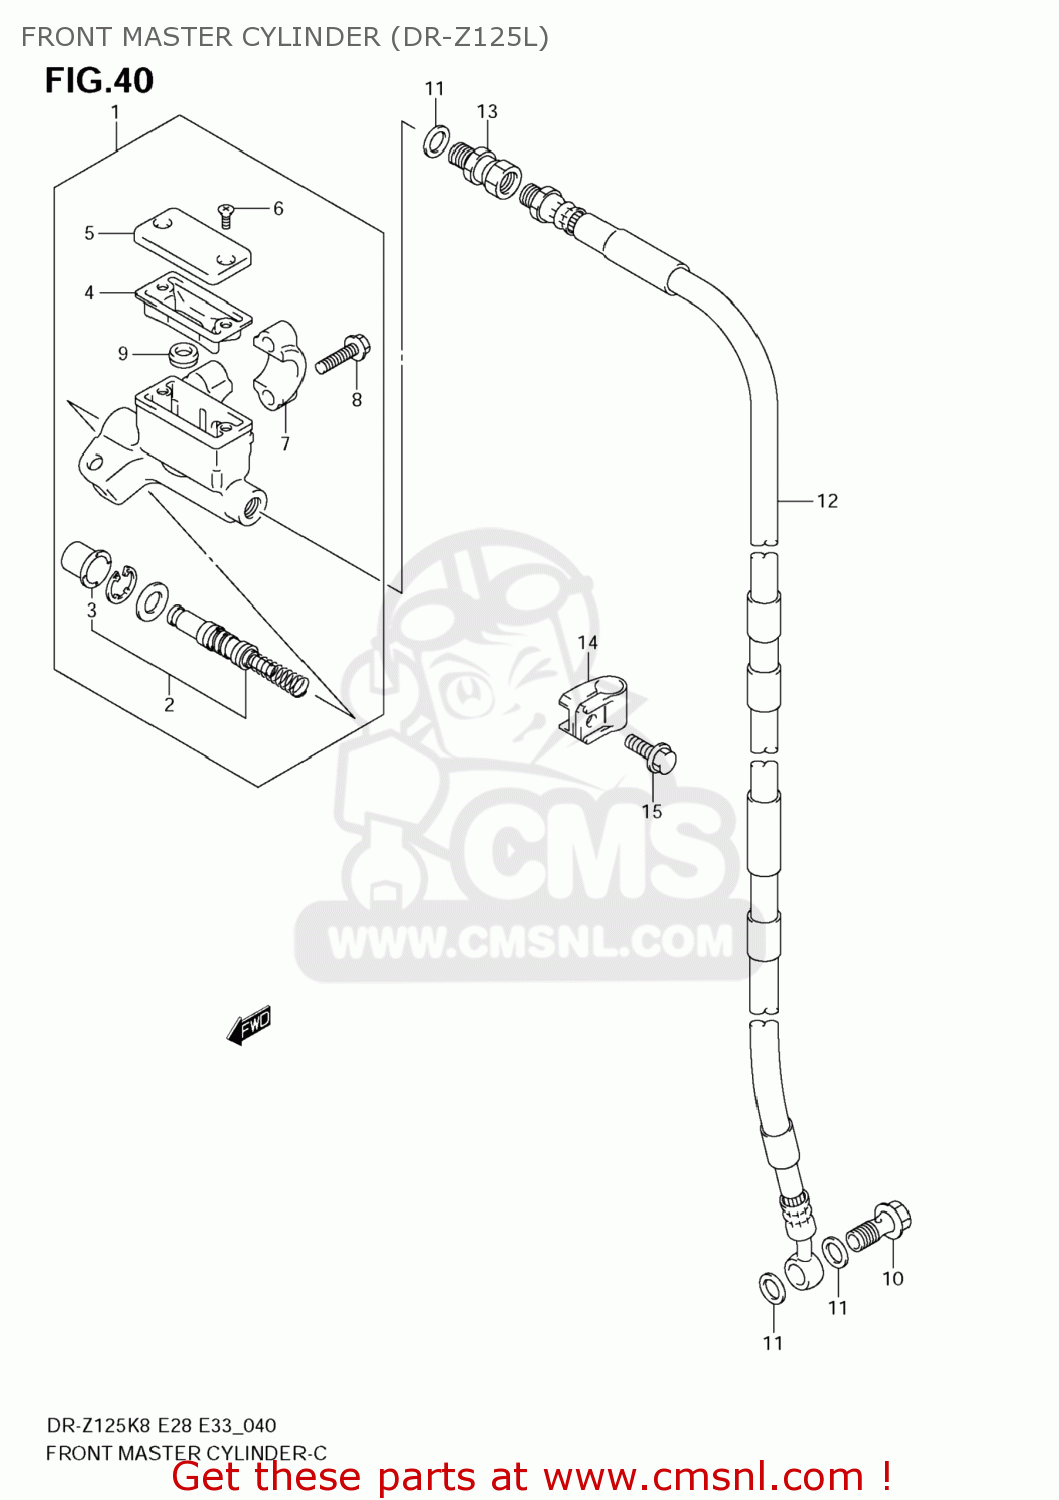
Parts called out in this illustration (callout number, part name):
1	CYLINDER ASSY,FR MASTER
2	PISTON & CUP SET
3	BOOT
4	DIAPHRAGM
5	CAP
6	SCREW
7	HOLDER
8	BOLT
9	SEPARATOR
10	BOLT UNION
11	WASHER(10X15X1.5)
12	HOSE,FR BRAKE
13	ADAPTOR,BRAKE HOSE
14	CLAMP,FR BRAKE
15	BOLT
